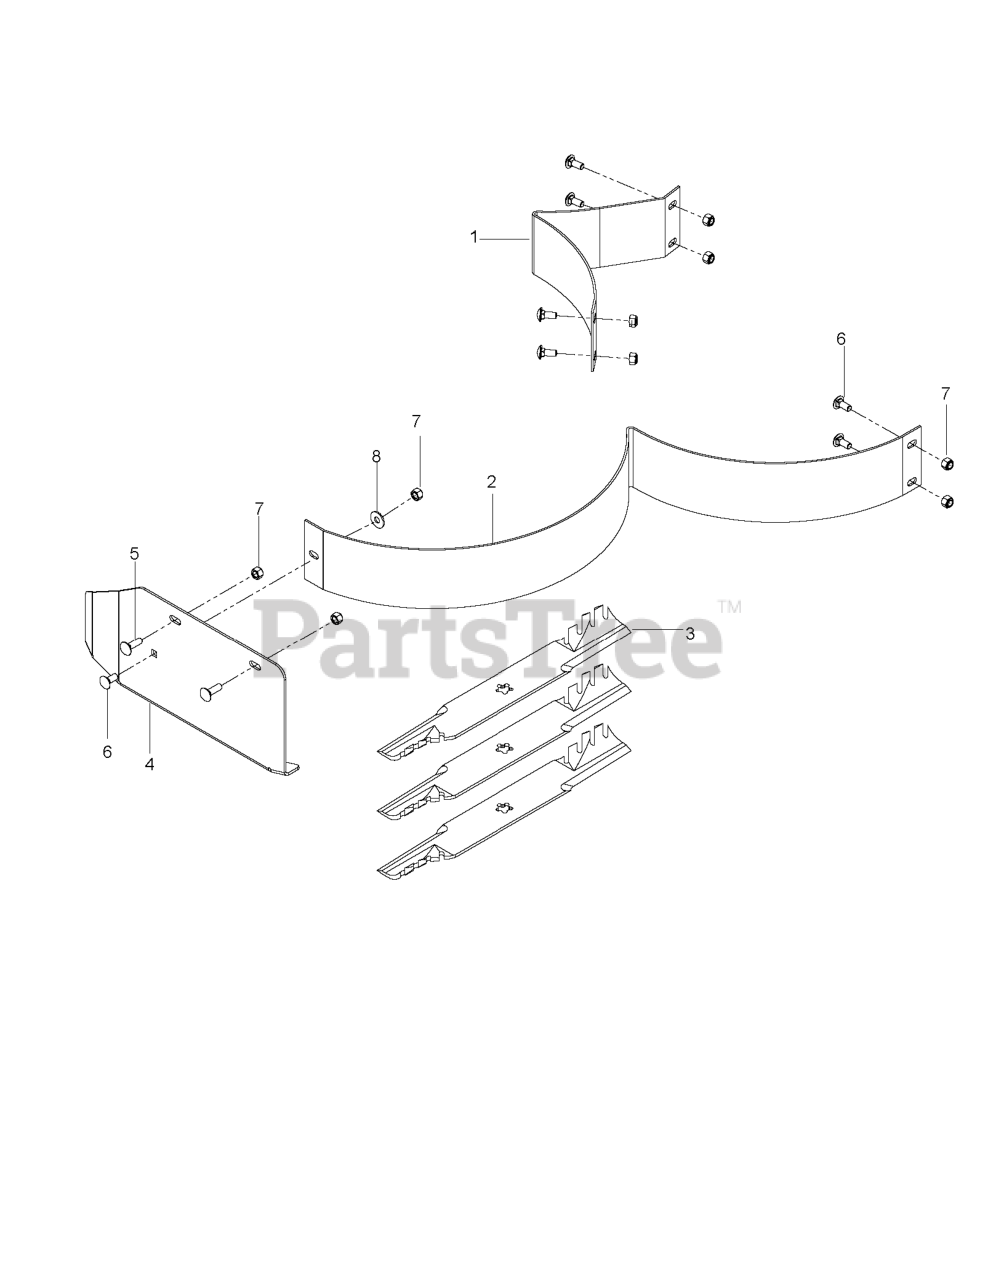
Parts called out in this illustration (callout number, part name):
1	52 MULCH BAFFLE - L.H. PAINTED
2	MULCH BAFFLE RH 52 - PAINTED
3	BLADE 18" GATOR
4	52 MULCH CAP - PAINTED
5	RHSNB 5/16C X 1
6	BOLT 5/16C X 3/4" CARRIAGE
7	NUT 5/16 NYLOC
8	WASHER 5/16 FLAT
